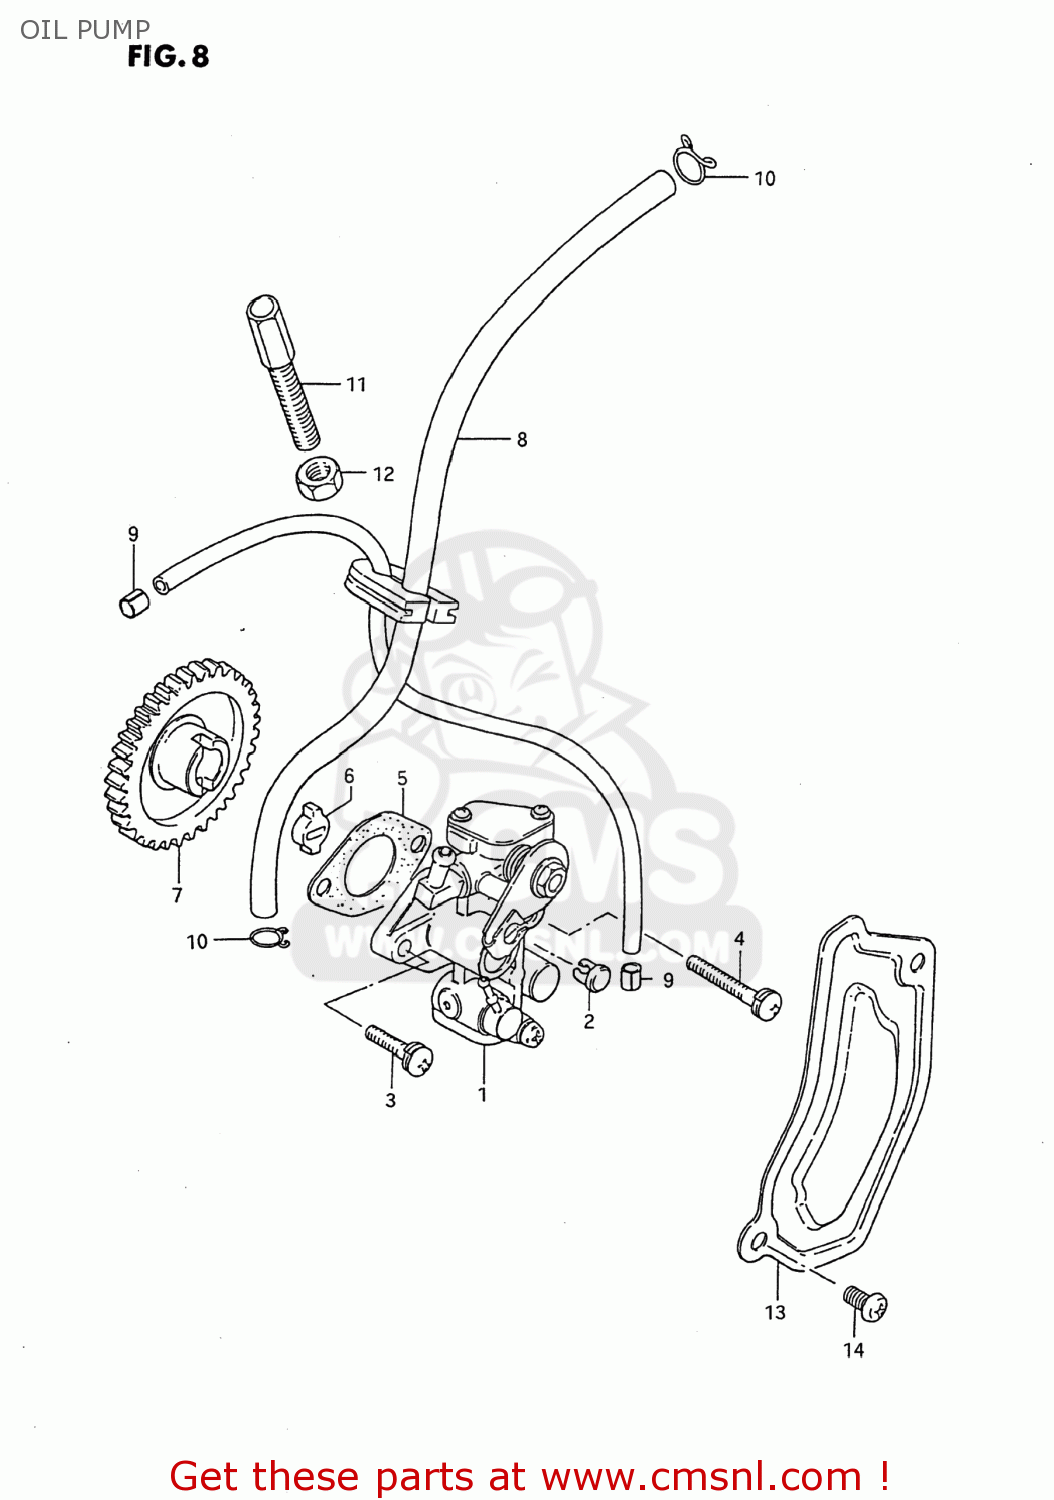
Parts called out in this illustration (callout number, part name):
1	PUMP ASSY,OIL
2	TERMINAL,CABLE
3	SCREW
4	SCREW
5	GASKET,OIL PUMP (NAS)
6	PIECE,OIL PUMP DRIVE
7	GEAR,OIL PUMP DRIVE
8	HOSE,OIL NO.2
9	CLIP
10	CLIP
11	BOLT
12	NUT
13	CAP,OIL PUMP INSPECTION
14	SCREW
